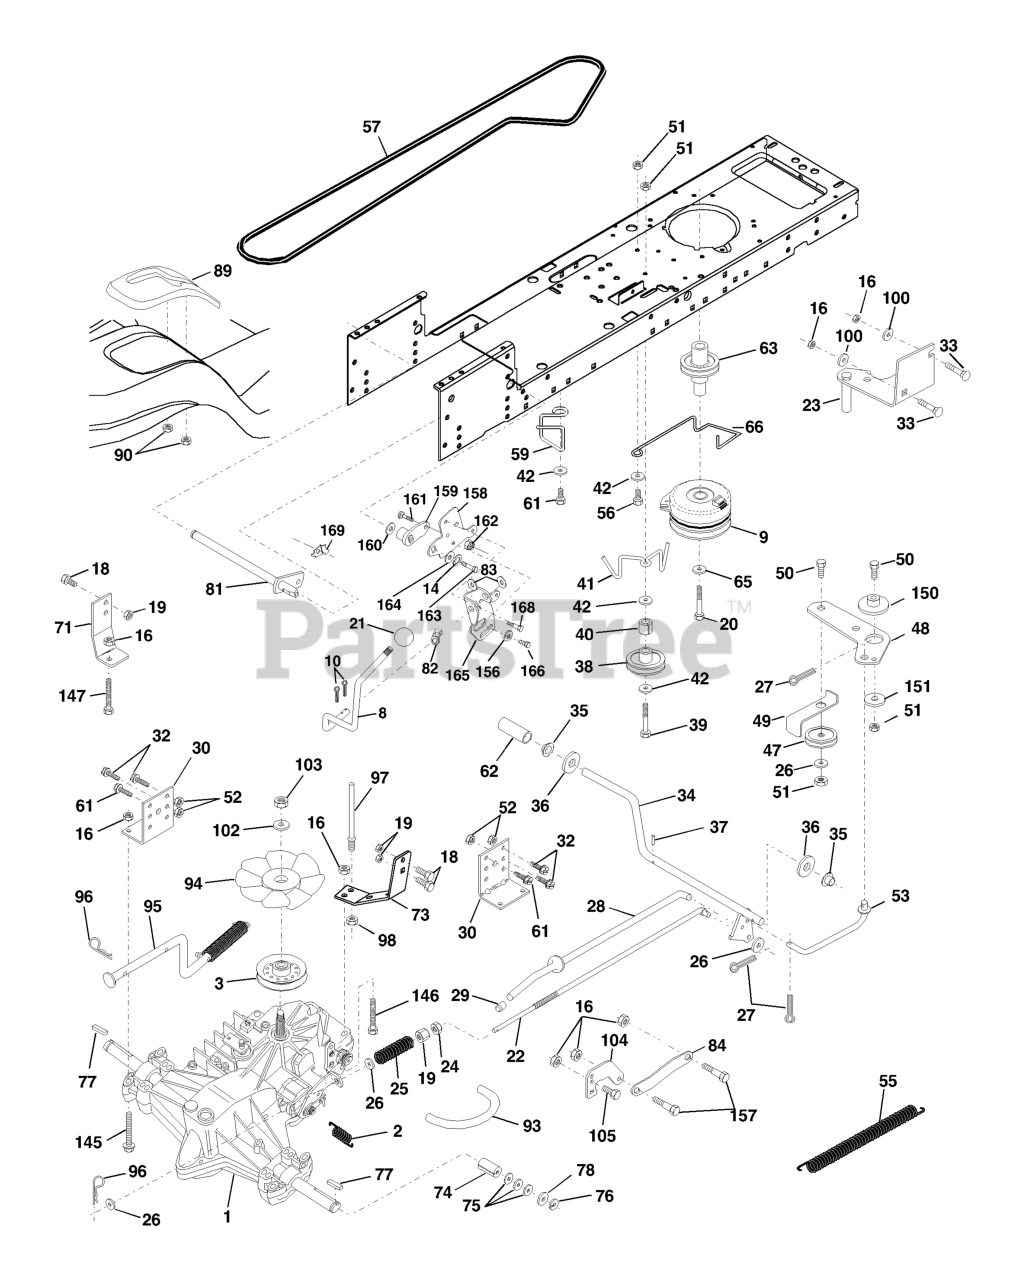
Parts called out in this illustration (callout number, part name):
1	Transaxle
2	SPRING BRAKE
3	PULLEY.4.20.HYDRO
8	ROD SHIFT FENDER ADJUST STLT
9	CLUTCH.ELECT.EVX.
10	PIN COTTER
14	LOCKWASHER
16	NUT.71038.31-18.HEX.NYLOCK
18	BOLT
19	NUT
20	BOLT HEX
21	KNOB.DUCKHEAD.1/2
22	ROD BRAKE HYDRO
23	BRACKET, ASM CLUTCH MTG
24	NUT
25	SPRING ROD LT
26	WASHER
27	COTTER PIN
28	ROD BRAKE PARK LT
29	PLUNGER CAP
30	BRACKET TRANSAXLE
32	BOLT
33	RP BOLT 5/16-18 X3/4 ZN/YEL GR
34	SHAFT, FOOT PEDAL
35	BEARING.NYLON
36	WASHER LT
37	DRIVE PIN
38	FLAT IDLER PULLEY
41	KEEPER.BELT.IDLER.FLAT
42	WASHER
47	IDLER PULLEY
48	BELLCRANK, CLUTCH
49	RETAIN BELT
50	BOLT
52	LOCKNUT
53	LINK, CLUTCH LT
55	SPRING, RETURN LT
59	KEEPER CENTER SPAN
61	SCREW
62	PEDAL COVER T
63	PULLEY, CLUTCH ELECT EVX
65	LOCKWASHER
66	KEEPER BELT ENGINE
71	STRAP TORQUE LH HYDRO
73	STRAP TORQUE RH HYDRO
74	SPACER SPLIT
77	SQUARE KEY
81	Shaft Asm Cross Tapered 500 18"
82	SHIFT SPRING
83	WASHER
84	Link Transaxle Hydr 0500
89	SHIFT CONSOLE
90	NUT.PUSH.3/16
93	LINE FUEL HYD 4"
94	FAN 7" HYDRO
95	CONTROL ARM, BYPASS HYDRO
96	RETAINER M
97	KEEPER BELT RH
100	WASHER M
103	NUT.HEX.1/2-20
104	ARM, CONTROL HYDRO
109	ADAPTOR FAN HYDRO
145	BOLT
146	Bolt Hex Flghd 5/16-18 x 2-1/4
147	Bolt Hex Flghd 5/16-18 x 1-1/2
150	BUSHING.BELLCRANK.GRD.DR
151	WASHER 12/32X2X10GA
156	WASHER.SRRTD.5/16
157	BOLT SHOULDER 5/16-18
158	BRACKET
159	HUB
160	Washer 29/32 x 1/4 x 16 Ga
161	BOLT
162	NUT.CROWNLOCK.1/4
163	BOLT
164	Washer 5/8 x 0281 x 10 Ga
165	RP BRACKET
168	BOLT.SHOULDER.5/16-18X
169	PLATE.FASTENING.CROSS.SHAFT
